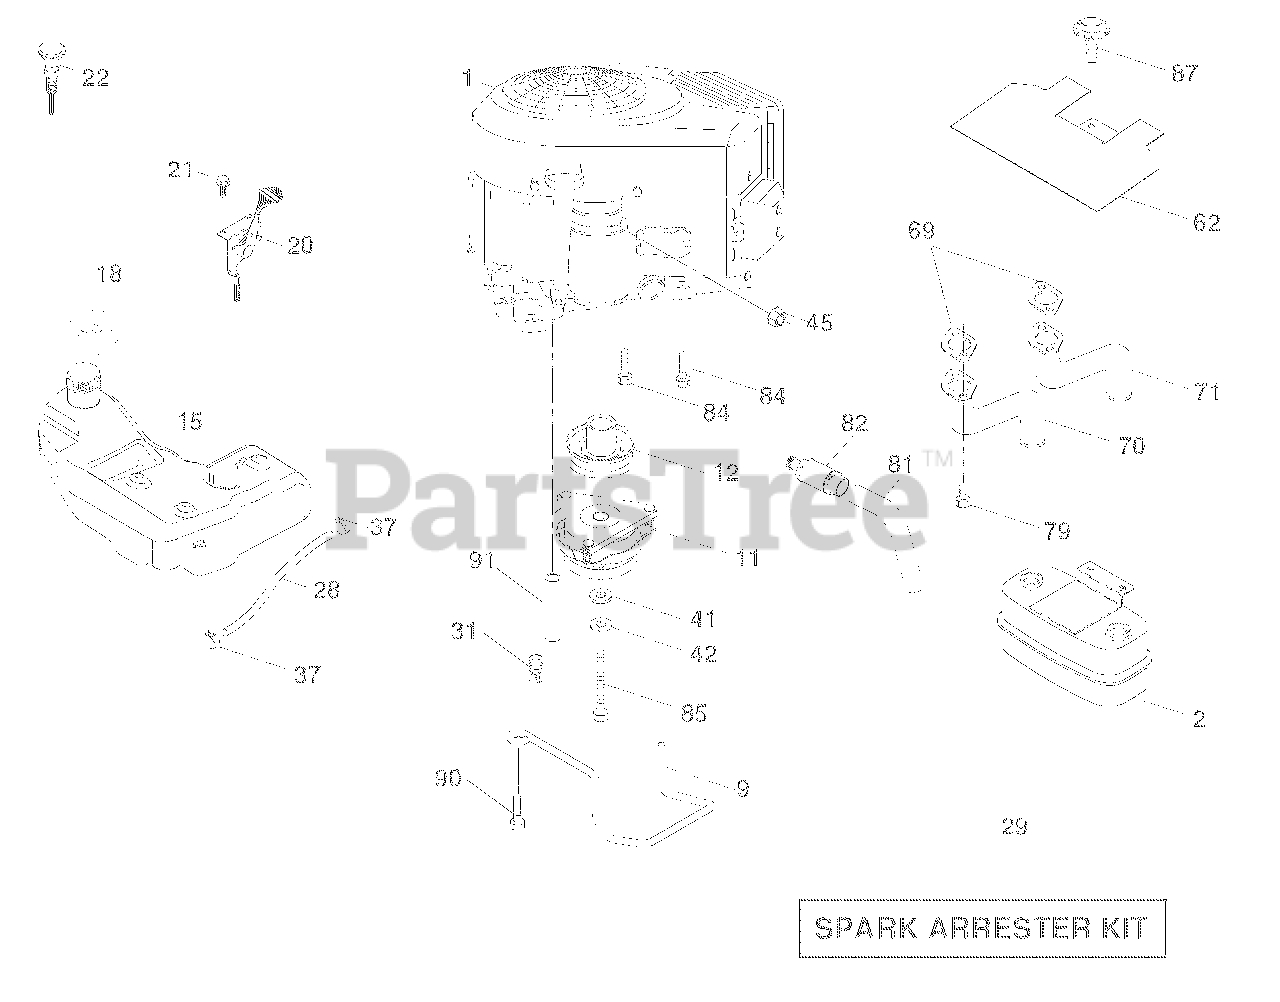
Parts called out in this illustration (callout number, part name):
9	Keeper Belt Engine
11	Clutch Electric
12	Pulley Engine
15	Tank Fuel 4.0
18	Cap Asm
20	Control Throttle
21	Screw 10 x 3/4 Single Lead Hex
22	Control Choke
28	Fuel Line
29	Spark Arrester Kit
31	Clip Push-In
37	Clamp Hose
41	Washer 1-1/2 OD x 15/32 ID x .250
42	Washer Lock 7/16
45	Nut Keps Hex 1/4-20 unc
62	Shield Heat Muffler
70	Tube Exhaust LH
71	Tube Exhaust RH
79	Screw Socket Head 5/16-18 x 1
81	Tube Drain Oil Easy
82	Plug Drain Oil
84	Screw 3/8-16 x 1-1/4
85	Bolt Hex 7/16-20 x 3.75 Gr. 5
87	Bolt 5/16-18 unc x 1 w/Sems
90	Screw 3/8-16 x 1
